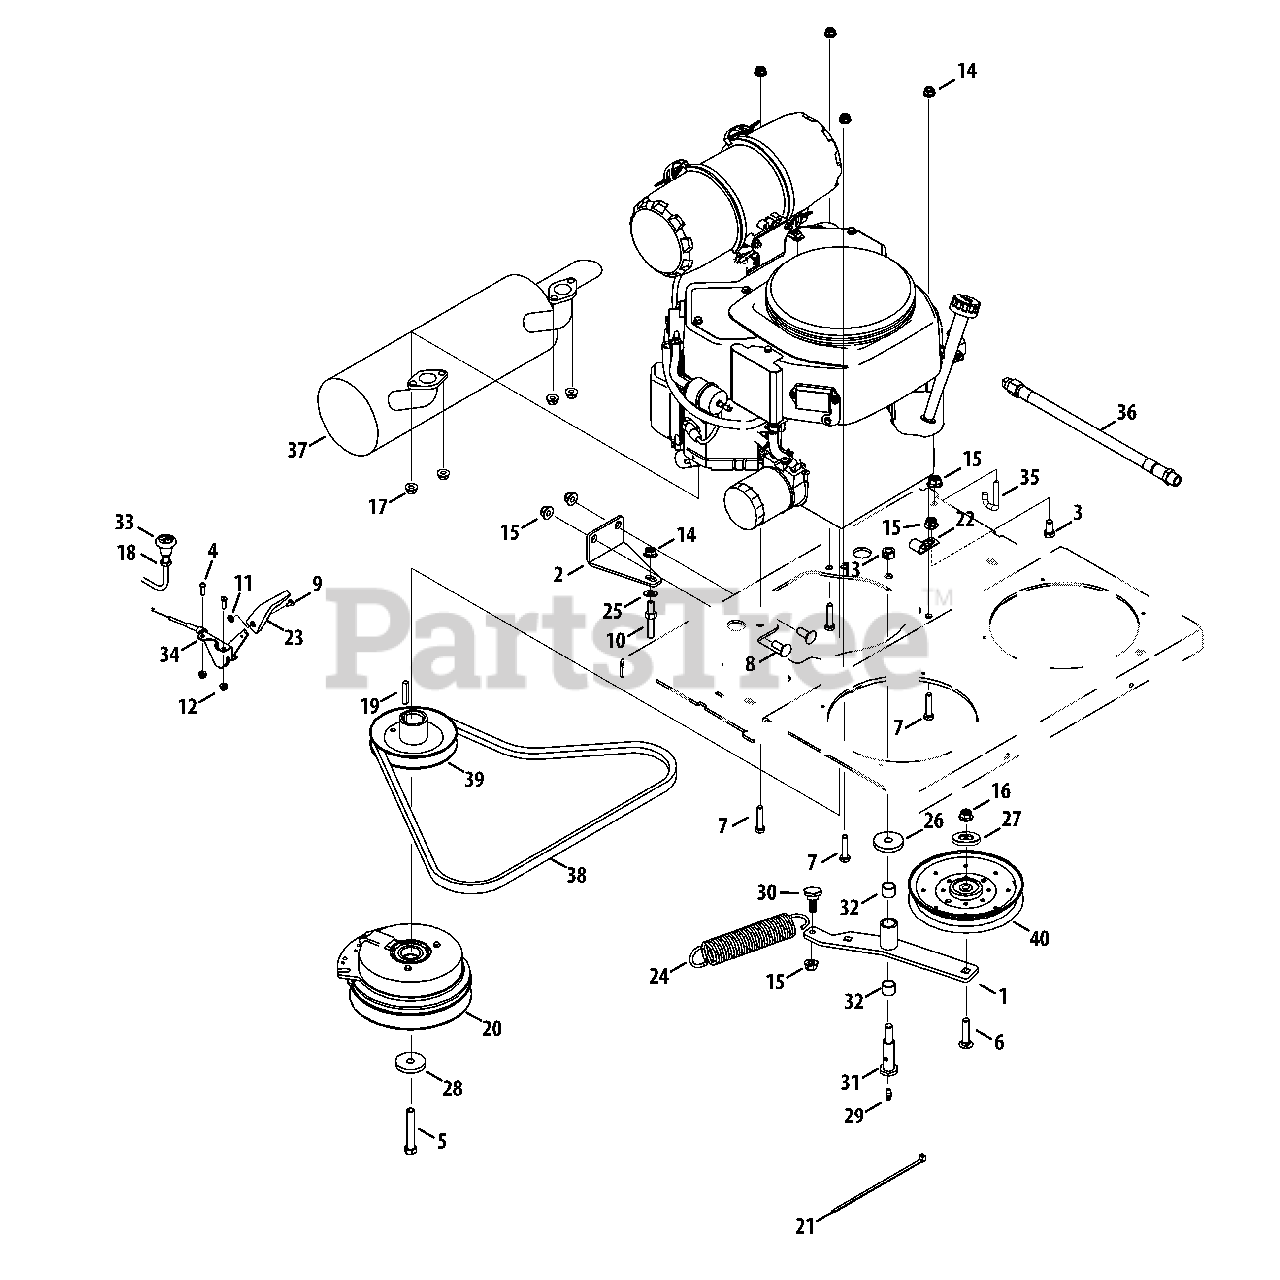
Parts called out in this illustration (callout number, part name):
1	Idler Bracket
2	Clutch Retainer Bracket
3	Hex Cap Screw, 3/8-16 x .75
4	Screw, #10-24 x .625
5	Hex Cap Screw, 7/16-20 x 2.75
6	Carriage Bolt, 3/8-16 x 1.00
7	Hex Cap Screw, 5/16-18 x 1.50
8	Carriage Bolt, 3/8-16 x 1.00
9	Screw, #8-32 x .375
10	Stud, Pivot Ball Joint
11	Nut, #8-32, Hex
12	Nut, #10-24, Hexlock
13	Nut, 7/16-14, Hexlock
14	Nut, 5/16-18, Flangelock
15	Nut, 3/8-16, Flangelock
16	Nut, 3/8-16, Flangelock
17	Nut, M8-1.25, Hexlock
18	Jam Nut, 3/8-24
19	Key, 1/4 x 1.50
20	Electric PTO Clutch
21	Cable Tie
22	Clip, .407 x 1.80
23	Throttle Control Knob
24	Extension Spring, 1.5 x 7.5
25	Washer, .344 x .688 x .065
26	Washer, .471 x 1.50 x .225
27	Pulley Cap
28	Washer, .471 x 1.50 x .225
29	Grease Fitting
30	Shoulder Screw, .625 x .302, 3/8-16
31	Shoulder Bolt, .625 x 1.947, 7/16-14
32	bearing, .638 x .753 x .615
33	Choke Control Cable
34	Throttle Cable
35	Transmission Spring Hook
36	Oil Drain Hose
37	Muffler
39	Drive Pulley
40	Idler Pulley
